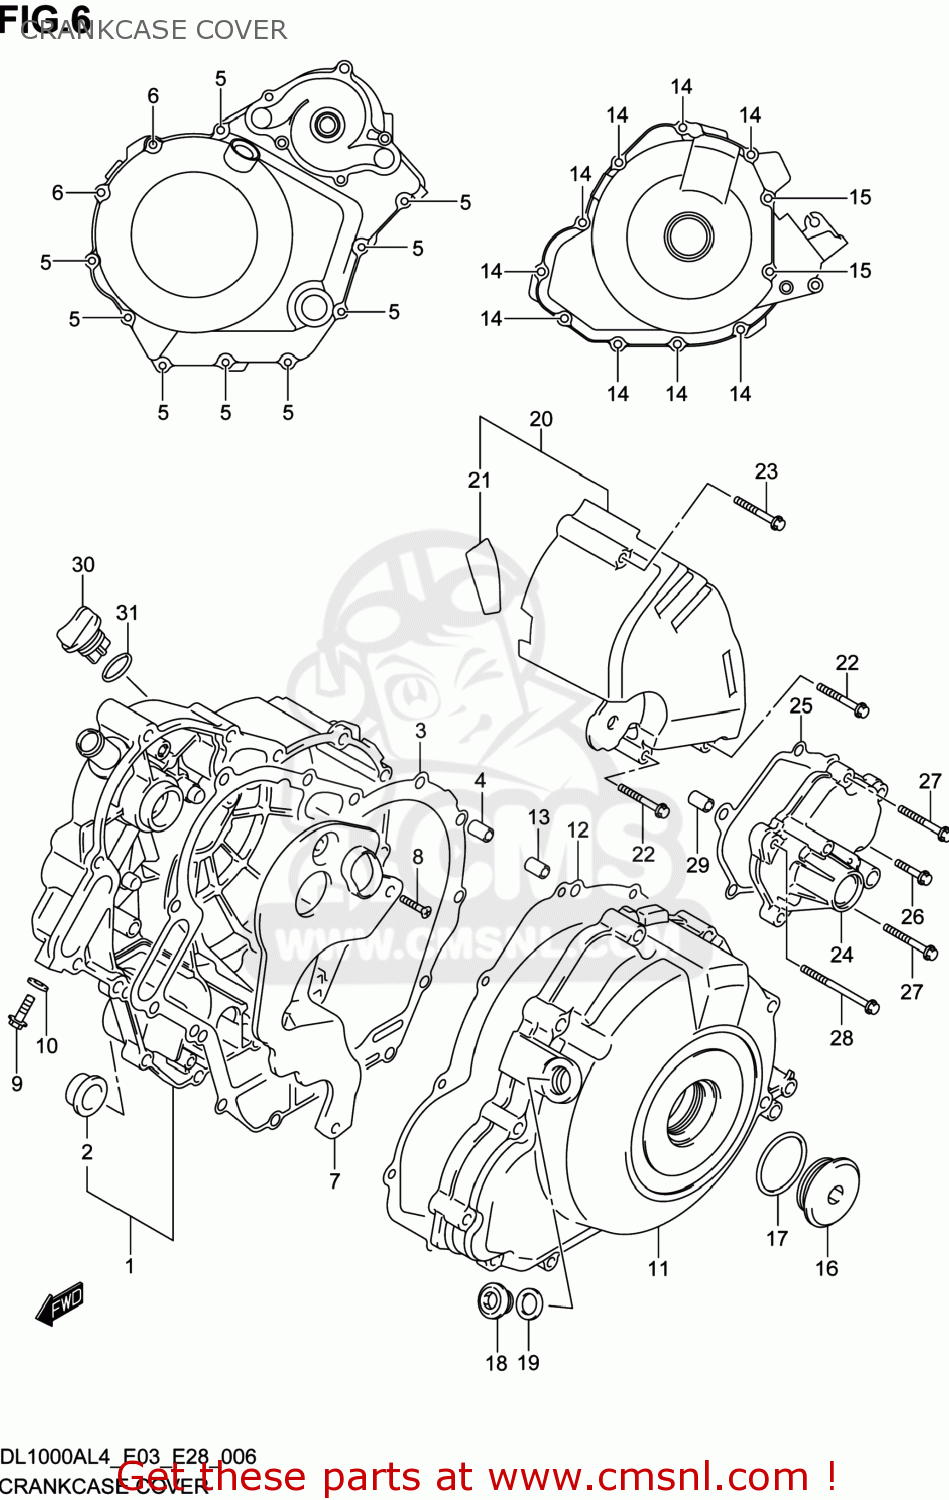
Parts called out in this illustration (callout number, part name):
1	COVER,CLUTCH
2	LENS,OIL LEVEL CHECK
3	GASKET,CLUTCH COVER (NAS)
4	PIN
5	BOLT(6X30)
6	BOLT(6X75)
7	SEPARATOR,OIL
8	SCREW
9	BOLT
10	GASKET(6.4X11.5X0.8) (NAS)
11	COVER,MAGNETO
12	GASKET,MAGNETO COVER (NAS)
13	PIN
14	BOLT(6X35)
15	BOLT(6X80)
16	PLUG
17	O RING(D:3.1,ID:32.7)
18	PLUG,14X12
19	GASKET(13.8X18.8X4.8) (NAS)
20	COVER,ENG SPROCKET
21	SHEET,SPROCKET COVER
22	BOLT(6X35)
23	BOLT(6X60)
24	COVER,GEAR SHIFT
25	GASKET,GEAR SHIFT COVER (NAS)
26	BOLT(6X105)
27	BOLT
28	BOLT
29	PIN
30	PLUG,ENGINE OIL FILLER
31	O RING(D:3.1,ID:16.8)
